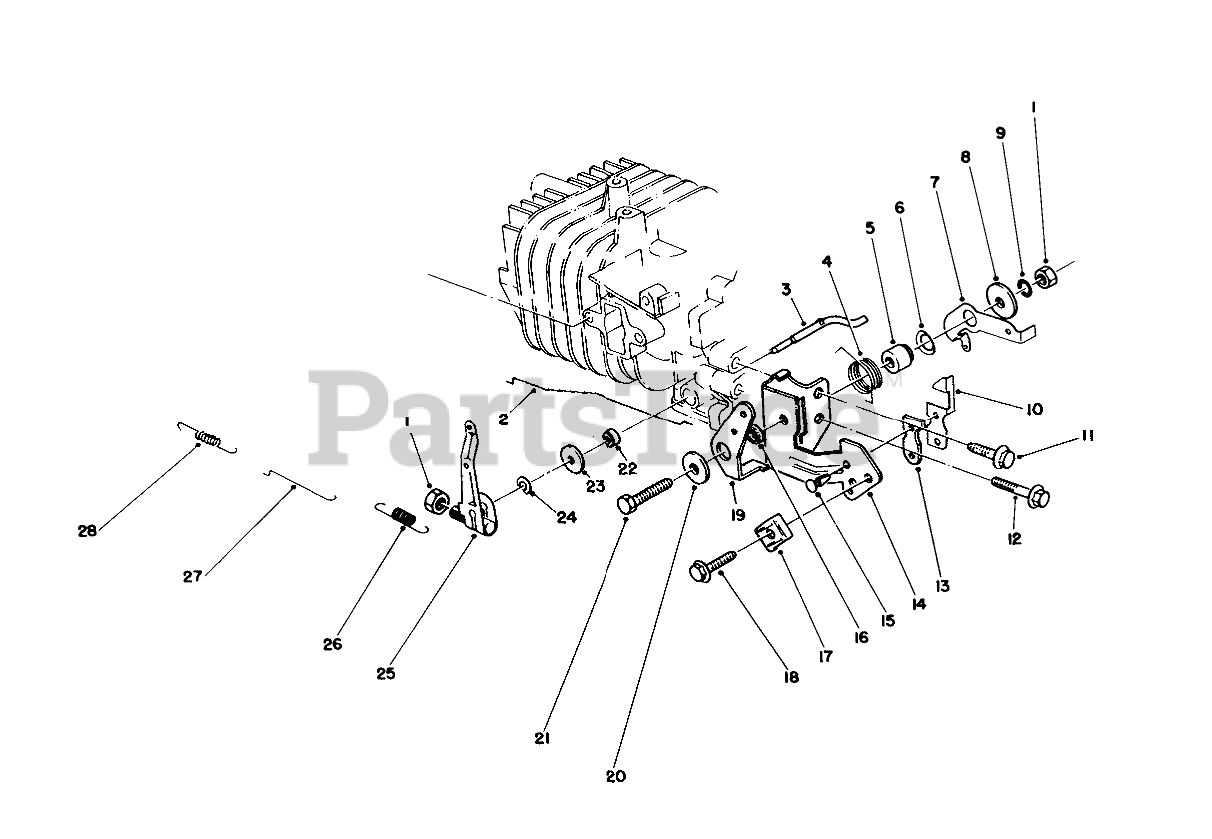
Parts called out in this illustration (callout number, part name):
1	CARB STUD BOLT
2	CHOKE ROD
2	GASKET-AIR CLEANER
3	Shaft-Govemor
3	CHOKE VALVE
4	SPRING-CHOKE LEVER
4	SPRING
5	Gov Lever Spacer
5	BUSHING
6	Washer-Gov. Spring Lever
6	SCREW
7	LEVER-SPRING, GOVERNOR
7	SHAFT-CHOKE
8	WASHER
8	SHAFT
9	LOCKWASHER
9	PLATE
10	TERMINAL-KILL SWITCH
10	Screw-Throttle
11	PILOT JET
12	GASKET
13	INSULATOR-KILL SWITCH
13	SHIELD
14	BRACKET-THROTTLE, CONTROL
14	INSULATOR
15	KILL SWITCH RIVET
15	GASKET-CARB
16	SPACER-CHOKE LEVER
16	Pin
17	CLAMP
17	NEEDLE
18	MAIN JET (76.3)
19	LEVER-CONTROL, CHOKE
19	FLOAT
20	WASHER
20	GASKET
21	Bowl-Float
22	SEAL-OIL
22	GASKET
23	WASHER
23	Bolt
24	E-RING
25	GOVERNOR ARM
26	SPRING-GOVERNOR
27	ROD-CARBURETOR
28	SPRING
